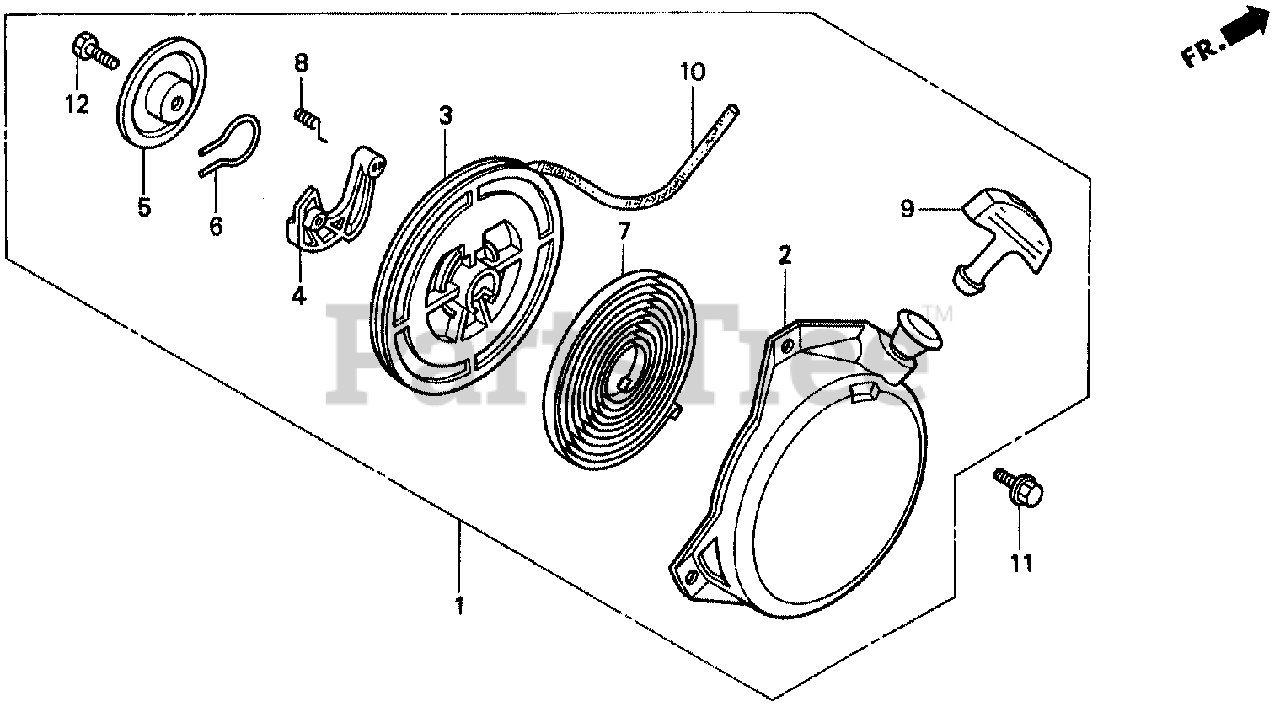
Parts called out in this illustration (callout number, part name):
1	STARTER ASSY., RECOIL
2	CASE, RECOIL STARTER
3	REEL, RECOIL STARTER
4	RATCHET, STARTER
5	PLATE, FRICTION
6	SPRING, FRICTION
7	SPRING, RECOIL STARTER
8	SPRING, RETURN
9	KNOB, STARTER
10	ROPE, RECOIL STARTER
10	ROPE (#4X55")
11	BOLT, FLANGE (6X8)
12	BOLT, HEX. (6X12)
